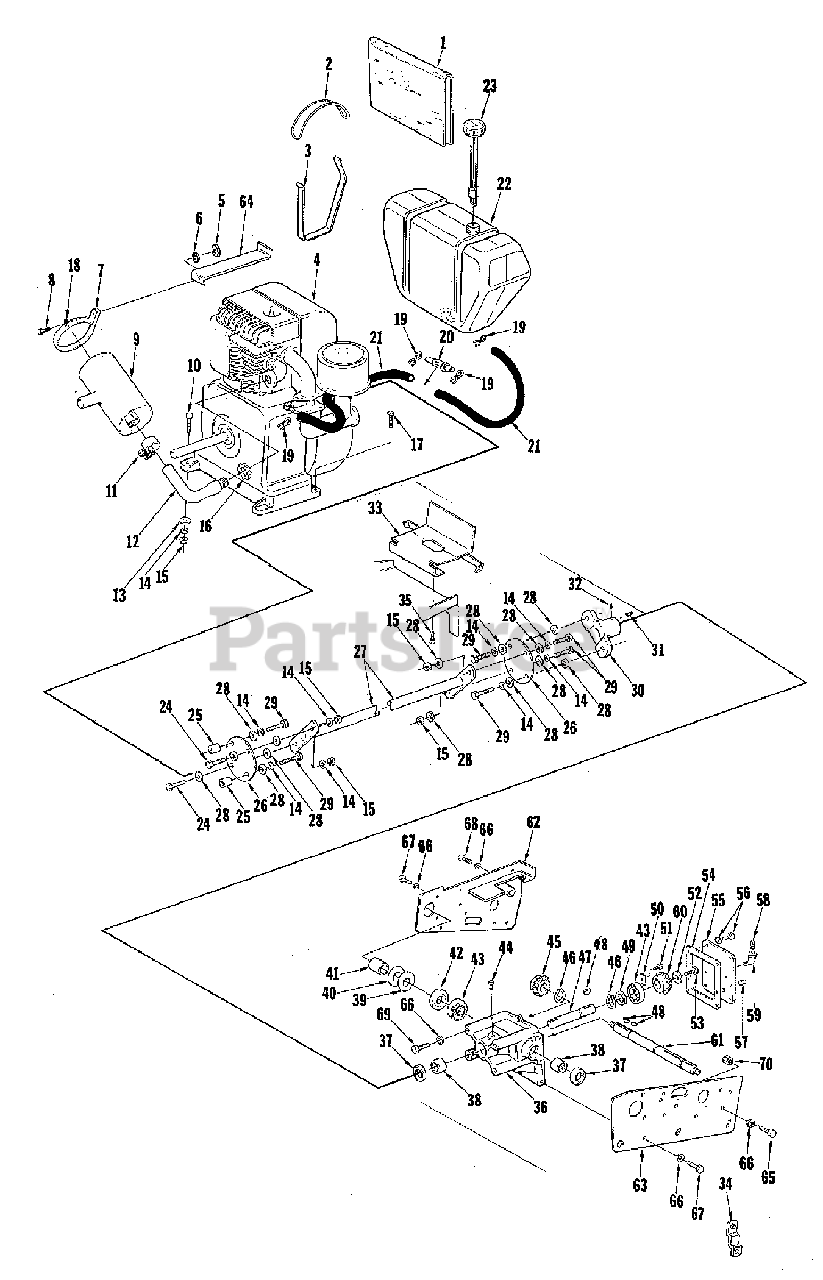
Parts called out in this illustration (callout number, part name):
1	INSULATION, Fuel Tank
2	STRAP, Fuel Tank (Upper)
3	STRAP, Fuel Tank
5	NUT, Hex, 5/16-18
6	WASHER, Lock, 5/16
7	STRAP, Muffler
8	SCREW, Hex Head Cap, 5/16-18 x 1
9	MUFFLER, Exhaust
10	SCREW, Hex Head Cap, 3/8-16 x 1-1/2
11	CLAMP, Muffler w/Fasteners
12	ELBOW & NIPPLE ASSEMBLY
14	WASHER, Lock, 3/8
15	NUT, Hex Fin, 3/8-16
17	SCREW, Rectangle Head, 3/8-16 x 1-5/16
18	WASHER, Flat, 11/32"
20	FILTER, Fuel
21	HOSE, Fuel 11"
23	CAP, Fuel Tank w/Guage
24	SCREW, Hex Head Cap, 3/8-16 x 1-1/2
25	SPACER, Drive Shaft
26	COUPLING, Drive Shaft
27	SHAFT ASSEMBLY, Drive
28	WASHER, Special
29	SCREW, Hex Head Cap, 3/8-16 x 1-1/4
30	FLANGE, Drive Shaft
31	KEY, Parallel, Special
32	SETSCREW, Hex Socket, 3/8-24 x 5/16
33	SUPPORT ASSEMBLY, Fuel Tank
34	CLIP, Spring (T-16S)
35	SCREW, Hex Head Cap, 5/16-18 x 1/2
36	HOUSING, Bevel Gear
38	BEARING, Needle
40	SHIM, Use as Required
43	BEARING, Ball
45	GEAR, Bevel Driven
46	RING, Retaining
47	SHAFT, Driven
50	PLATE, Bearing Clamp
53	SCREW, Hex Head Cap, 5/16-18 x 3/4
55	COVER, Housing
56	SCREW, Cap w/Internal Tooth Washer, 1/4-20 x 5/8
57	PLUG, Pipe, 1/4
58	PLUG, Pipe, 3/8
59	ELBOW, Street, 3/8 x 90 Degrees
60	GEAR, Bevel Driver
61	SHAFT, Driver
62	PLATE, Side R.H. (T-16S)
62	PLATE, Side, R.H. (T-10)
62	PLATE, Side, R.H. (T-16H)
63	PLATE, Side, L.H. (T-10, T-16S)
63	PLATE, Side, L.H. (T-16H)
64	BRACKET, Voltage Regulator
65	SCREW, Hex Head Cap, 7/16-14 x 1-1/4 (T-10)
66	WASHER, Lock (T-10)
66	WASHER, Lock (T-16S)
66	WASHER, Lock (T-16H)
67	SCREW, Hex Head Cap, 7/16-14 x 1 (T-10, T-16H)
67	SCREW, Hex Head Cap (T-16S)
68	SCREW, Hex Head Cap (T-16S)
68	SCREW, Hex Head Cap (T-16H)
69	SCREW, Hex Head Cap
70	NUT, Hex, 7/16-14 (T-16H)
